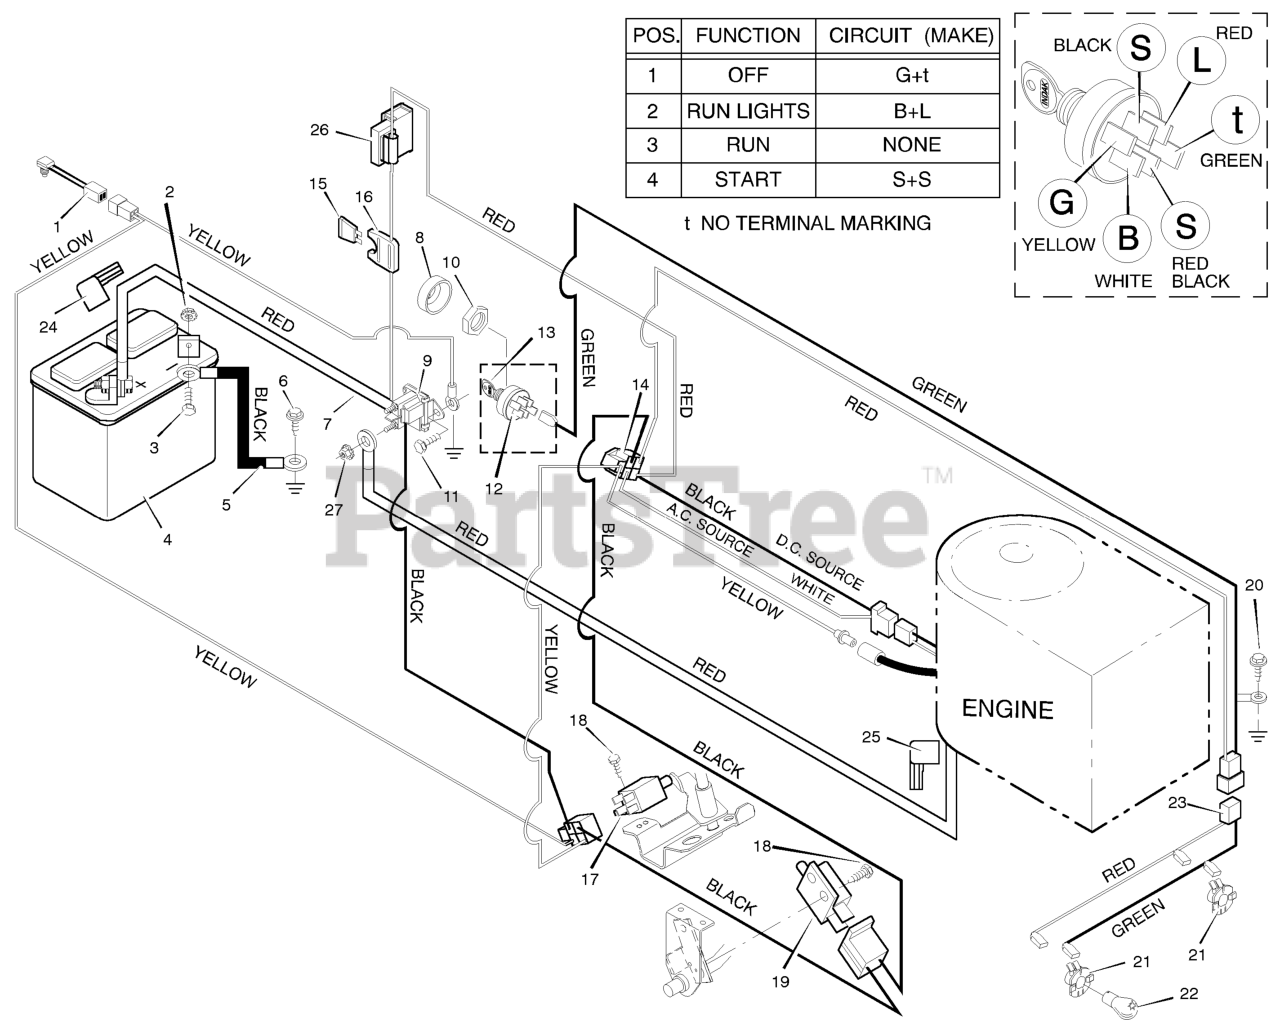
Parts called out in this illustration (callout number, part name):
1	Switch, Seat Sensor
2	Locknut
3	Bolt, Hex
4	Battery
5	Cable, Battery Ground
7	Cable, Red Battery
8	Cap, Ignition
9	Solenoid
10	Nut
12	Switch, Ignition
13	Key, Ignition
14	Harness, Chassis Wire
16	Holder, Fuse
17	Switch, Clutch
19	Switch, Clutch
20	Screw
21	Socket, Light
22	Bulb, Light
23	Harness, Light Wire
24	Cover, Terminal
25	Cover,
26	Ammeter
27	Locknut
